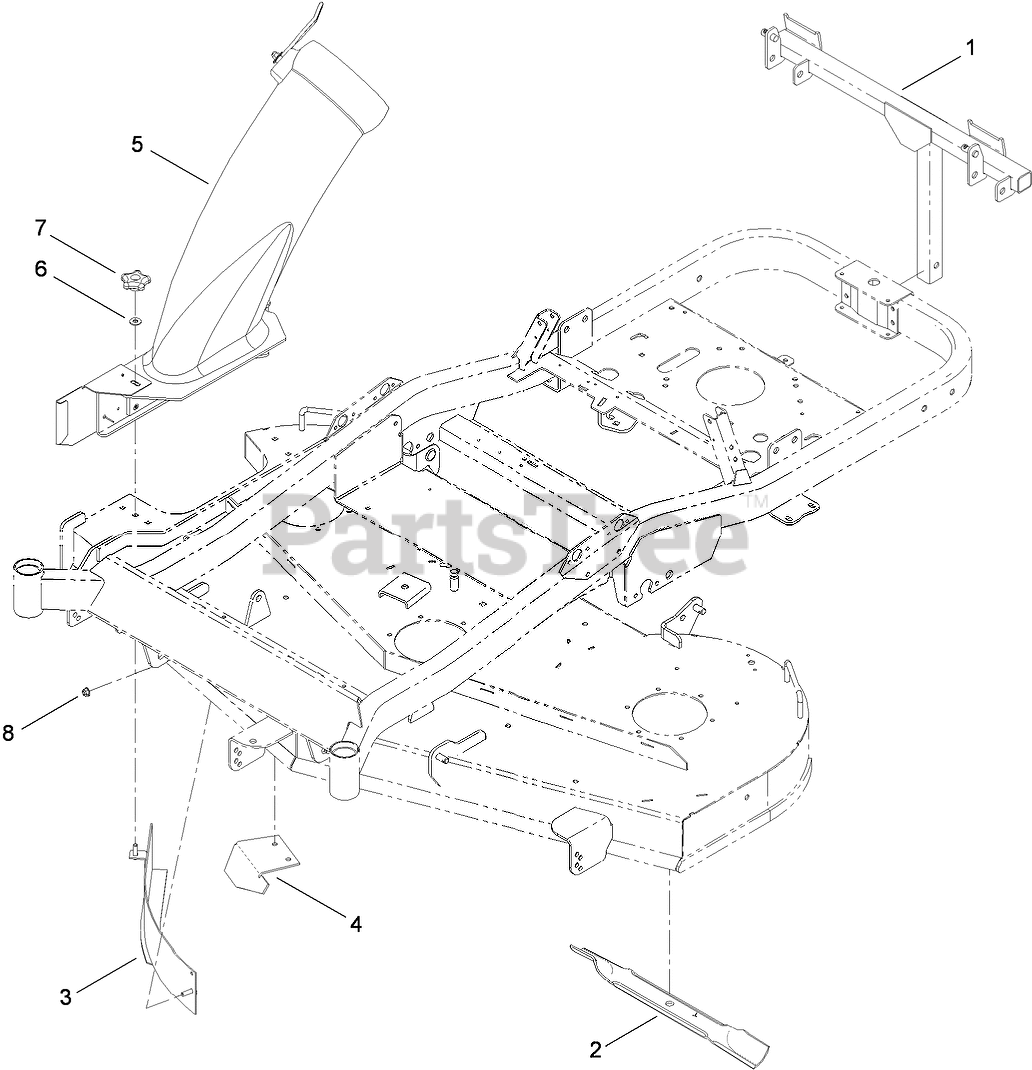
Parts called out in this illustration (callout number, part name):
1	FRAME-PIVOT
2	BLADE-20.50 INCH
3	BAFFLE-BAGGER
4	BAFFLE-CUTOFF
5	BAGGER BOOT ASM
6	WASHER-FLAT
7	KNOB-LOCKING
8	NUT-HF, NI
